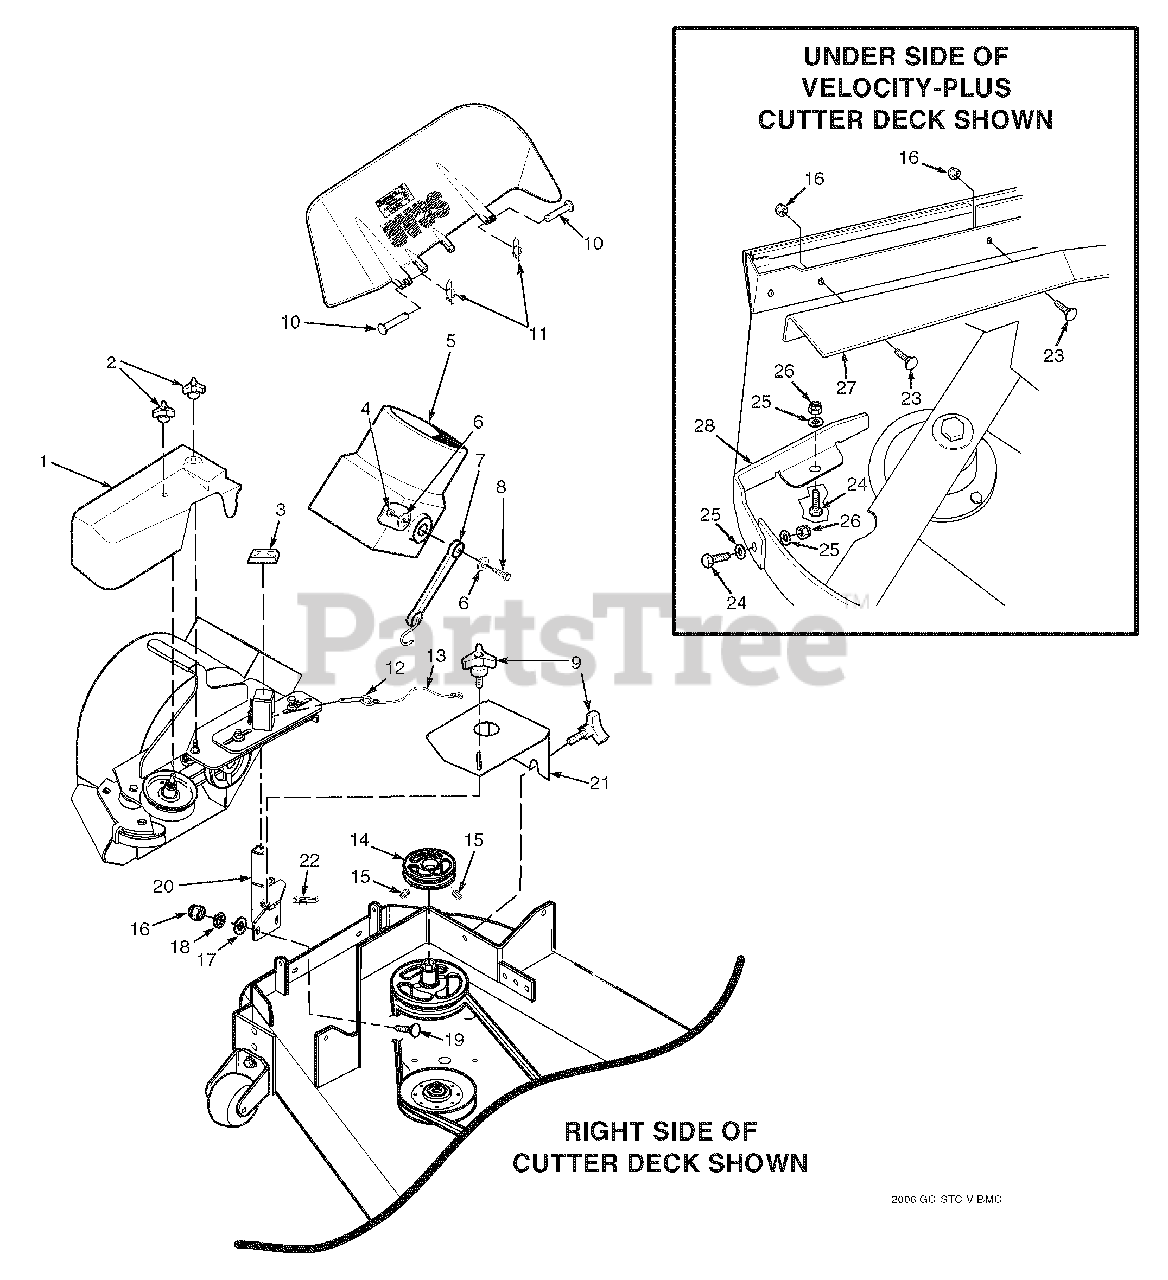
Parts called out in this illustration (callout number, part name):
1	Belt Cover, GC-61V
2	Wingnut, Plastic 3/8" Small
3	Cap, Square Vinyl
4	Nut, Elastic Stop 1/4-20
5	Adapter, Blower GC-STC
6	Flatwasher, 1/4-.312 x .750 x .065
7	Rubber Strap 7-3/4"
8	Bolt, Hex Head 1/4-20 x 1-1/4"
9	Knob W/Stud, 3/8-16 x 1-1/4"
10	Clevis Pin, 5/16 x 1-1/2"
11	Pin, Rue Cotter 5/16 Dia.
12	Pin, Ring 1/2 x 2-1/4"
13	Lanyard
14	Pulley, 5-1/2" Dia. 1.125 Bore
15	Setscrew, 5/16-18 x 3/8"
16	Nut, Elastic Stop 3/8-16
17	Lockwasher, 3/8"
18	Flatwasher, 3/8-.391 x .938 x .105
19	Bolt, Carr. 3/8-16 x 1-1/4" Grade 5
20	Mounting Post Weldment, Blower
21	Belt Cover, GC-61V
23	Bolt, Carriage 3/8-16 x 1"
24	Bolt, Hex Head 5/16-18 x 1"
25	Flatwasher, 5/16-.375 x .875 x .083
26	Nut, Elastic Stop 5/16-18
27	Baffle, Front 61" Deck
28	Baffle, Turbo 61" Deck
